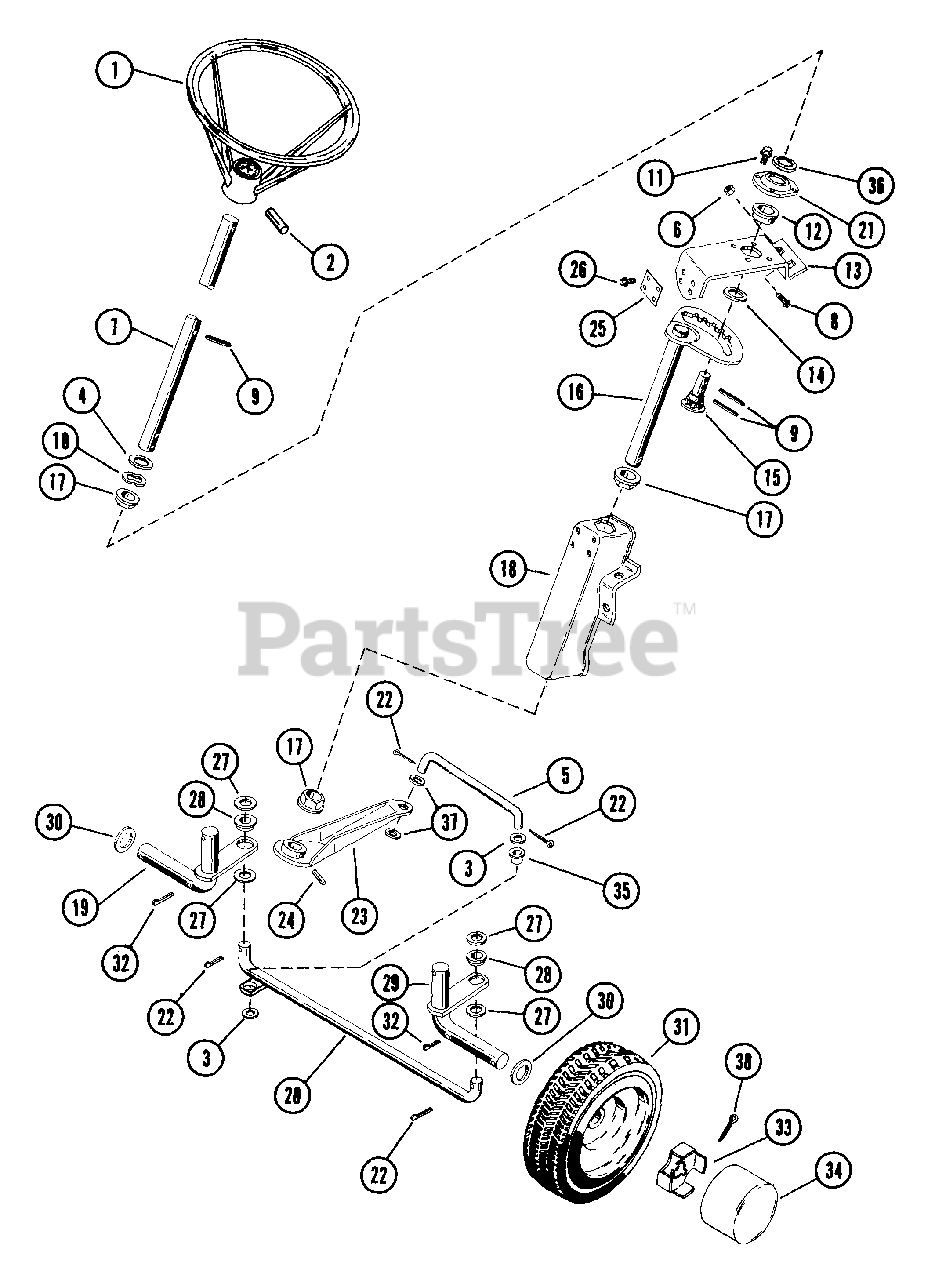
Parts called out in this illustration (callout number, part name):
1	STEERING WHEEL
2	PIN-ROLL .250X1.75
3	WSHR-FL-STL .382X.812X.023 PL
4	WSHR-FL-STL .755X1.375X.062 PL
5	STEERING LINK
6	NUT-LK .312-18 GR A PL
7	STEERING SHAFT
8	BLT-RDHDSQSHNK .31-18X.50 YZ
9	PIN-ROLL .188X1.00
10	SPRING WASHER
11	SCR-TAP 10-24X.25 CRSLPH PL 1A
12	BSHG-FLG .625X1.156X.375 SI
13	STEERING SUPPORT
14	WSHR-FL-STL .630X1.005X.062 PL
15	STEERING PINION
16	STEERING GEAR
17	FLANGE BUSHING
18	DEEP DRAW STEERING BOXES
19	R H WHEEL SPINDLE
20	TIE ROD
21	RETAINING PLATE
22	PIN-COTR .12X1.0 PL
23	STEERING ARM
24	PIN-GRV .188X1.25 TP A
26	BLT-SERHFWH .31-18X.75 PL
27	WSHR-FL-STL .505X.875X.024 PL
28	BSHG-FLG.500X.625X.312X.750NY
29	L H WHEEL SPINDLE
30	SPINDLE WASHER
31	FRONT WHEEL ASSEMBLY
31	TIRE 4.10/3.50-4
31	WHL
31	ZERK FITTING
31	BSHG-FLG .750X1.380X.750X1.557
32	PIN-COTR .12 X 1.25 PL
33	SPINDLE CUP
34	HUB CAP
35	BSHG-FLG .372X.500X.312X.625NY
36	PUSH NUT, .50
37	WSHR-FL-STL .406X.865X.094 PL
38	PIN-COTR .12X1.0 PL
